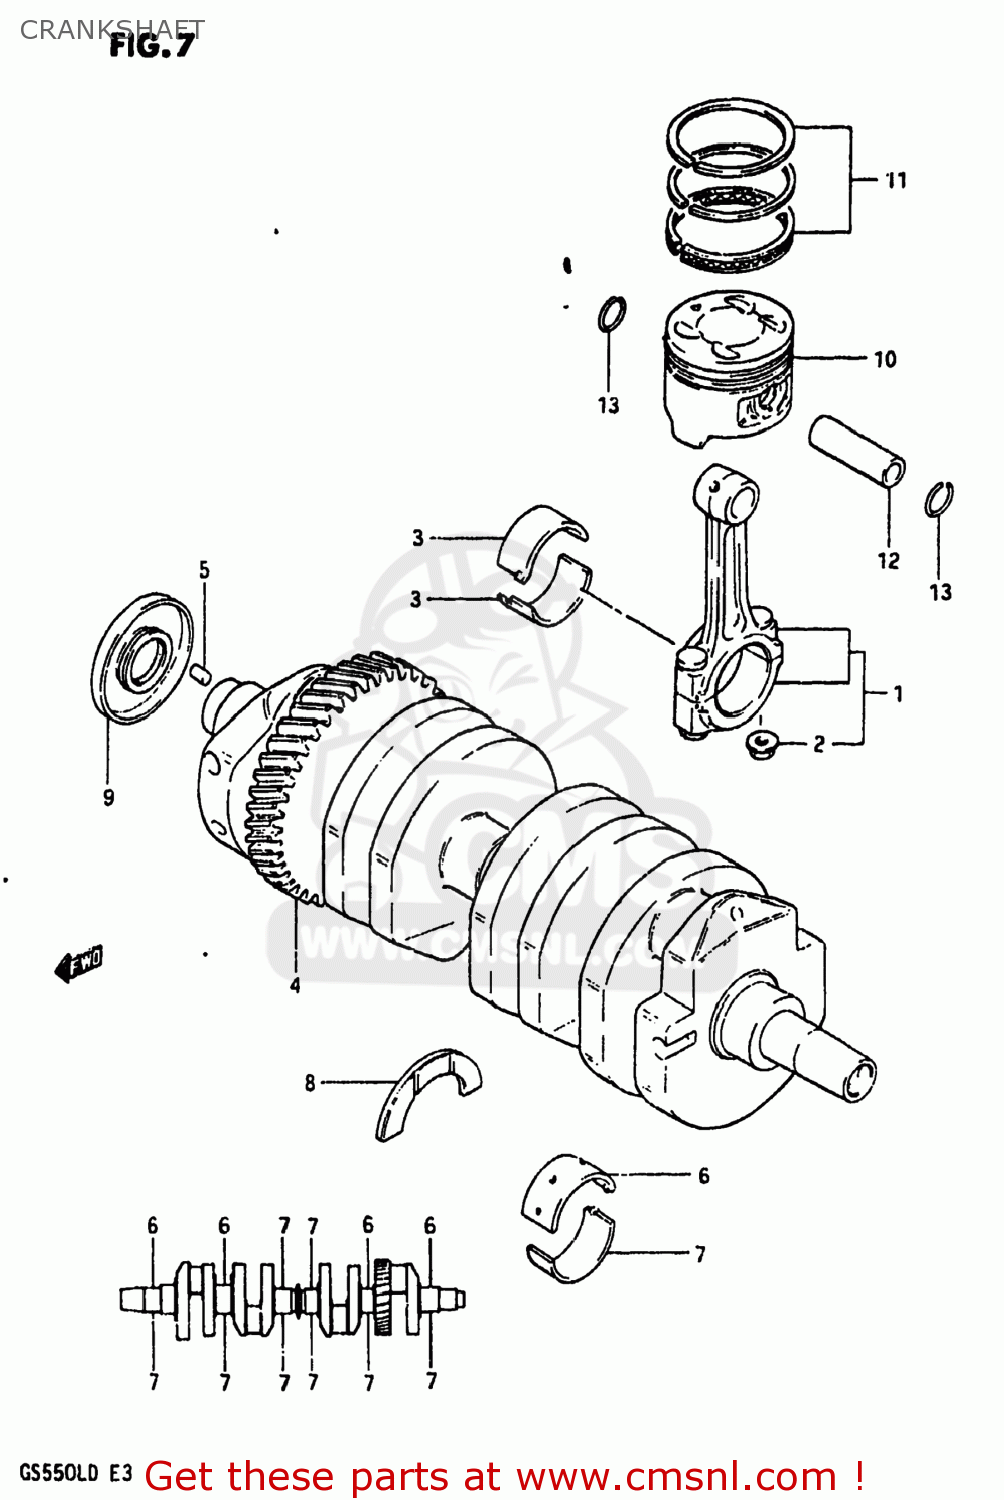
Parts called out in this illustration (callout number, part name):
1	ROD ASSEMBLY,CONNECTING
2	NUT
3	BEARING,CRANK PIN
4	CRANKSHAFT ASSEMBLY
5	PIN
6	BEARING,CRANKSHAFT
7	METAL CRANKSHAFT
8	PLATE,CRANK THRUST
9	OIL SEAL
10	PISTON
11	RING SET,PISTON
12	PIN,PISTON
13	CIRCLIP
